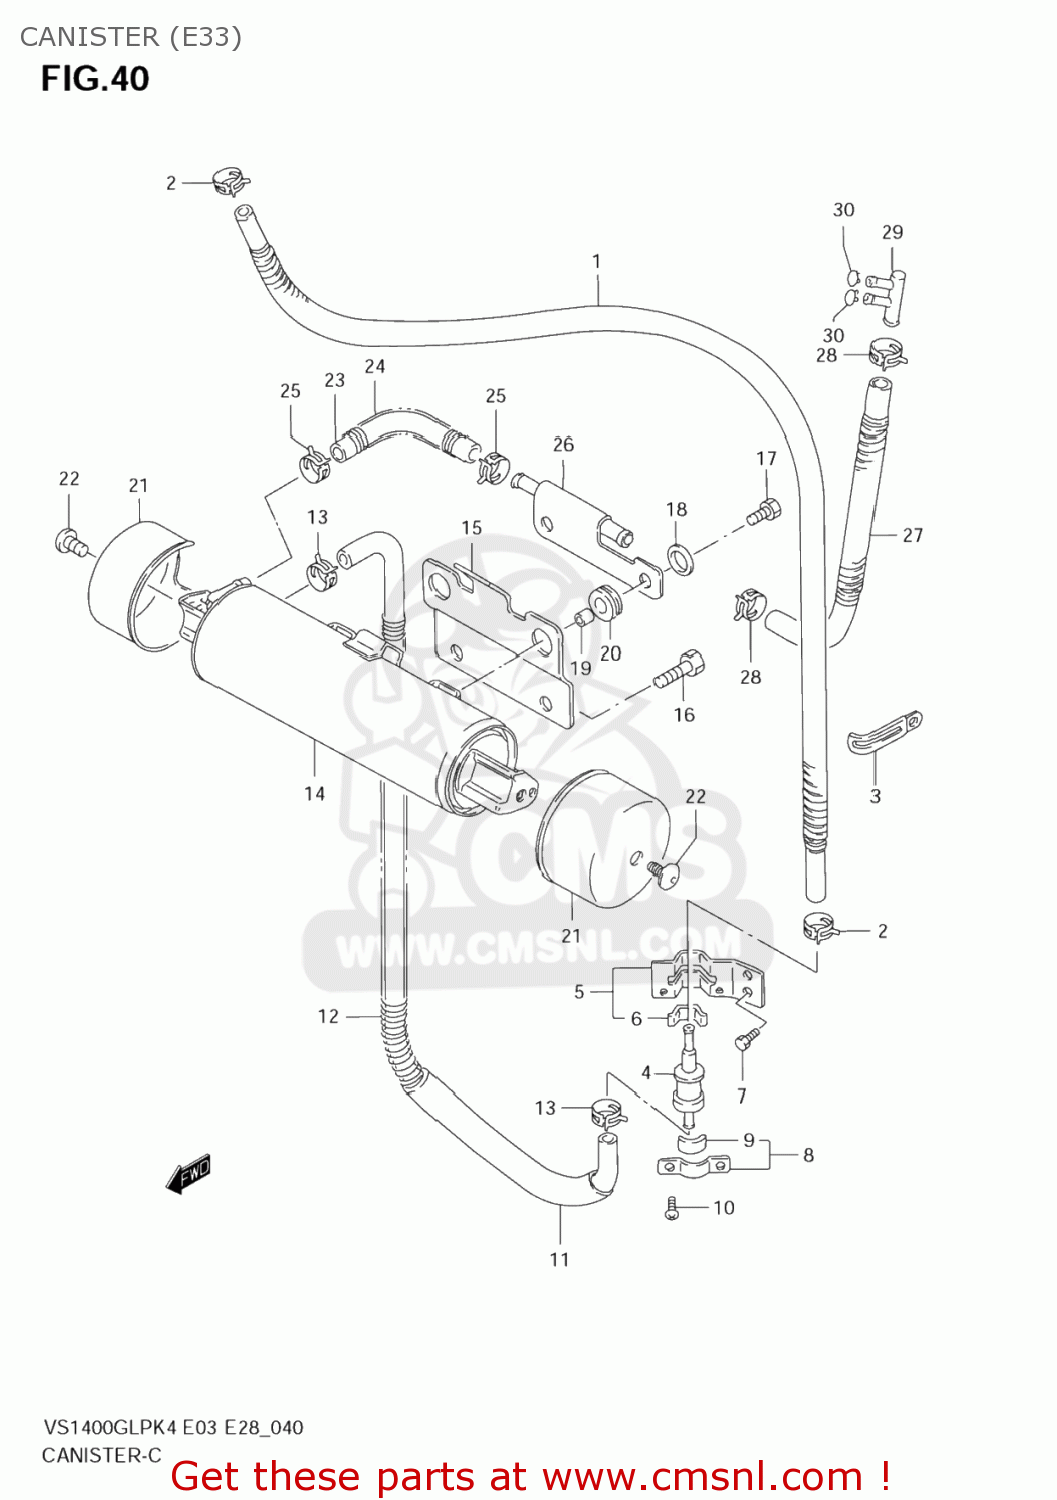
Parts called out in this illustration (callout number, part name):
1	HOSE,JOINT FUEL TANK
2	CLIP
3	CLAMP(L:80)
4	VALVE,FUEL TANK BREATHER
5	BRACKET,TANK BRTHR VALVE
6	CUSHION
7	BOLT
8	PLATE,FUEL TANK BREATHER NO.2
9	CUSHION
10	SCREW
11	HOSE,VALVE & CANISTER JOINT
12	SPRING
13	CLIP
14	CANISTER ASSY,CHARCORL
15	PLATE,CANISTER FITING
16	BOLT
17	BOLT
18	WASHER(6.5X22X1.6)
19	SPACER(6.1X9X7.5)
20	CUSHION
21	COVER,CANISTER
22	SCREW(6X10)
23	HOSE,CSTR PIPE JOINT
24	SPRING
25	CLIP
26	PIPE,CANISTER
27	HOSE,PIPE JOINT
28	CLIP
29	SEPARATOR
30	CLIP
